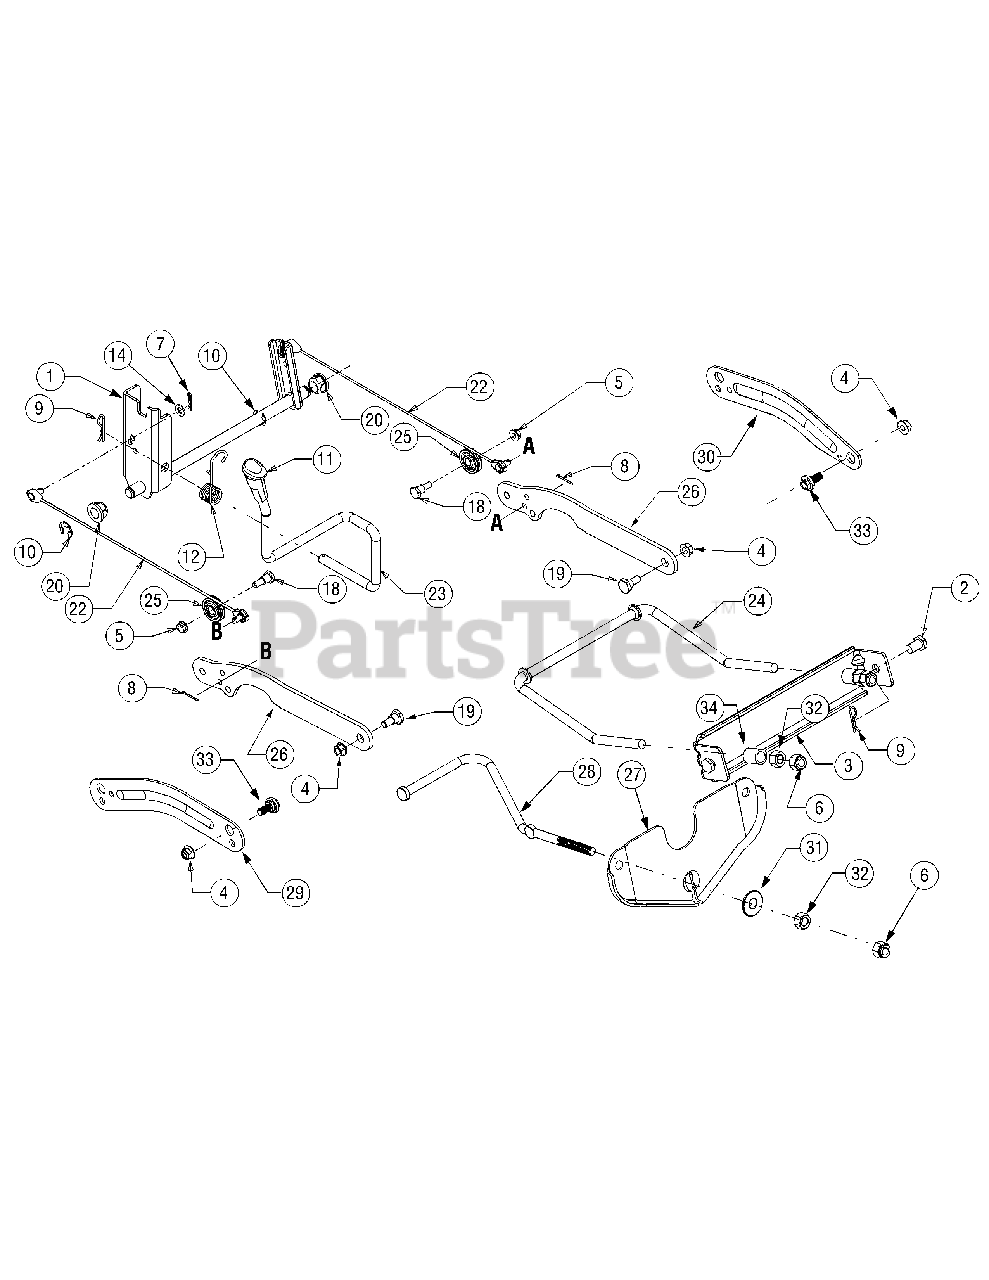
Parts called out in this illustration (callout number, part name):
1	Shaft Assembly, Lift
4	Nut, Nylon Lock, 3/8-16
5	Nut, Nylon Lock, 5/16-18, Gr5
6	Nut, Hex Lock, 1/2-13, Gr8, Nylon
7	Pin, Cotter, .072 Dia. x 1.13 Lg
8	Pin, Cotter, 3/32, 1.0
9	Pin, Click, .092 x 1.64 Lg
10	E-ring, .625 Dia. Shaft
11	Grip, Handle
12	Spring, Torsion
18	Screw, Hex Cap, 5/16-18x.620 Gr2
19	SHOULDER SCREW .498 DIA x .340
20	Bearing, Hex Flange
22	Cable, Lift, 16.16 Lg
23	Handle, Lift
24	Rod, Deck .5" Dia. (46-inch Decks)
24	Rod, Deck .5" Dia. (50-inch Decks)
25	Pulley, Roller
28	Rod, Deck, .448" Dia. (42-inch Decks)
31	Pivot Cup
32	HEX NUT 1/2-13
33	Shoulder Screw, 3/8-16
34	Spacer, .55 x .75 x 1.125 (50-inch Decks)
